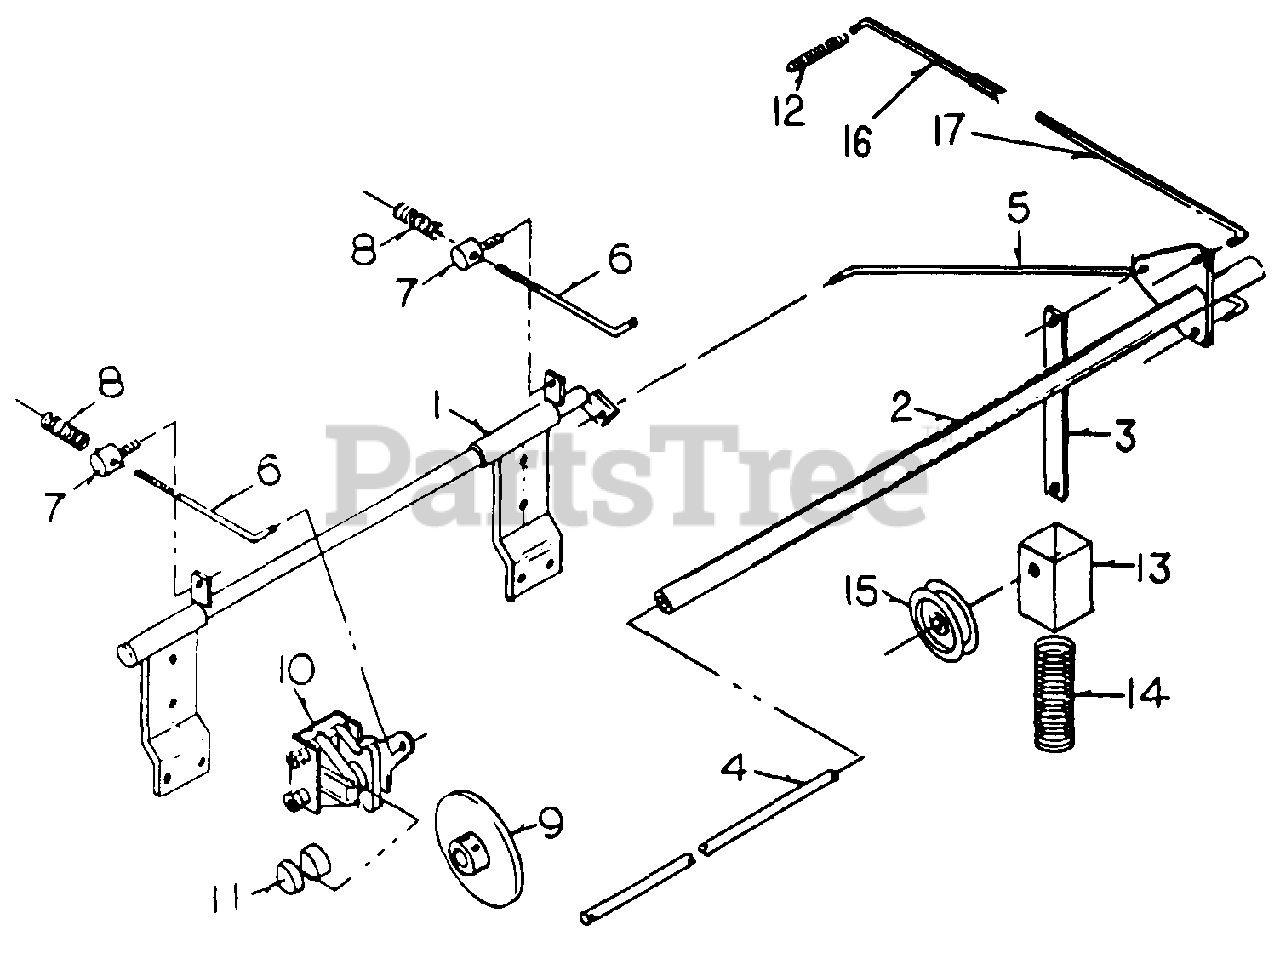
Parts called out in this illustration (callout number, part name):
1	BRAKE MOUNT & CROSS ROD ASS'Y
2	BRAKE CLUTCH CROSS ROD
3	CROSS ROD TO IDLER PULLEY LINKAGE
4	CROSS BAR PIN
5	CROSS ROD TO BRAKE LINKAGE
7	CALIPER ROD COLLAR
8	BRAKE CALIPER SPRING
10	BRAKE ASSEMBLY
12	BRAKE PEDAL SPRING
13	SPRING LOADED IDLER MOUNT
14	TRANSMISSION BELT IDLER SPRING
15	IDLER PULLEY
16	BRAKE ROD - adjustable
